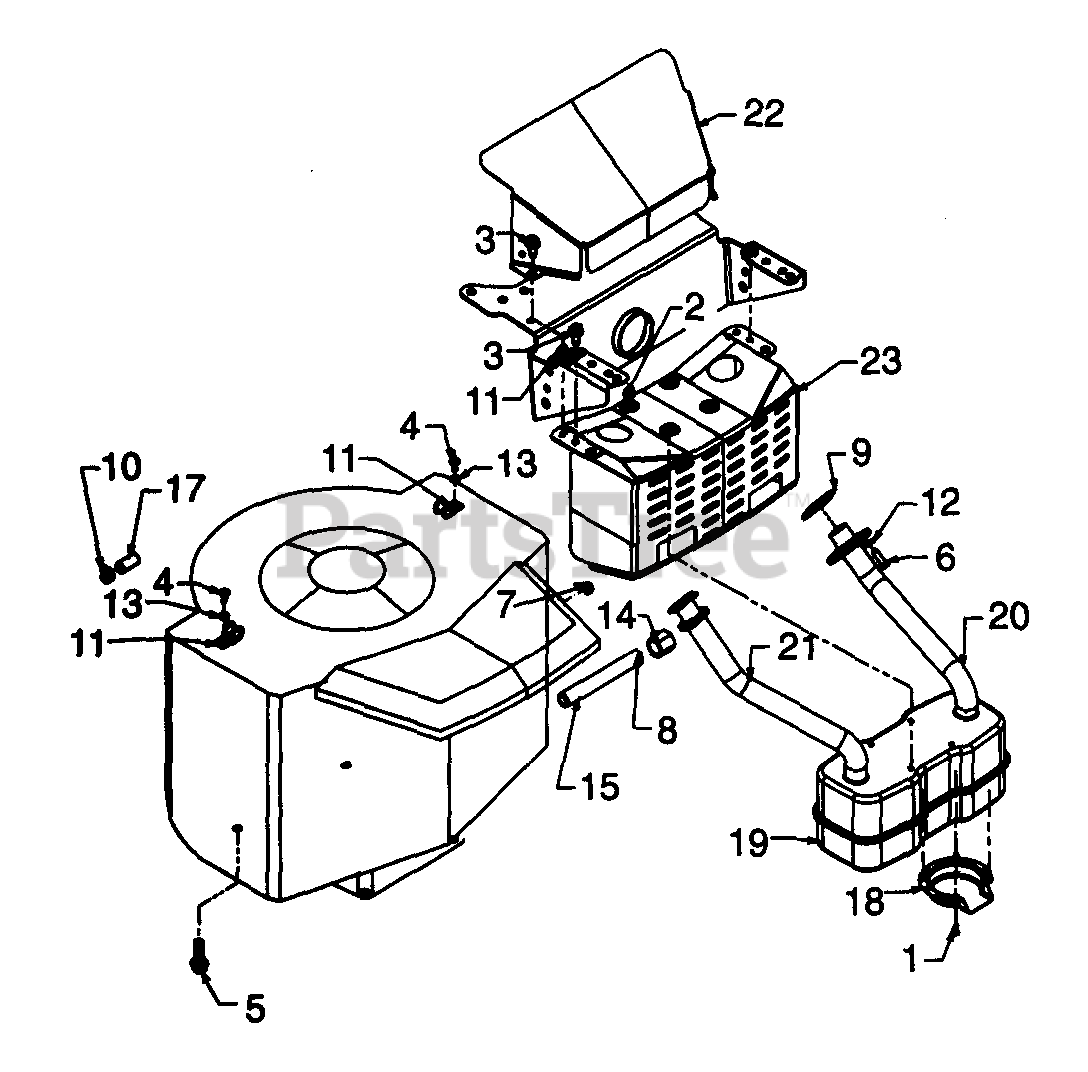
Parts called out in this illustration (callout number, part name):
1	Hex Tap Scr. #8-32 x .38" Lg.
2	Hex Wash. TT-Tap Scr. 1/4-20 x 5" Lg.
3	Hex Wash. TT-Tap Scr. 5/16-18 x .62" Lg.
4	Truss Mach. Scr. #10 x .5" Lg.
5	Hex Hd. Tap Scr. 3/8-16 x 1.25" Lg.
6	Hex Bolt 1/4-20 x .75"Lg.
7	Hex Sems Nut 1/4-20 Thd.
9	Exhaust Gasket
10	Hose Clamp
11	Clamp
12	L-Wash. 1/4" I.D.
13	Fl-Wash. .188" I.D. x .438" O.D.
14	Oil Drain Cap
15	Pipe Nipple 3/8 x 18 NPT.
17	Fuel Line 26" Lg.
18	Deflector: Muffler
19	Muffler
20	Exhaust Pipe - L.H.
21	Exhaust Pipe - R.H.
